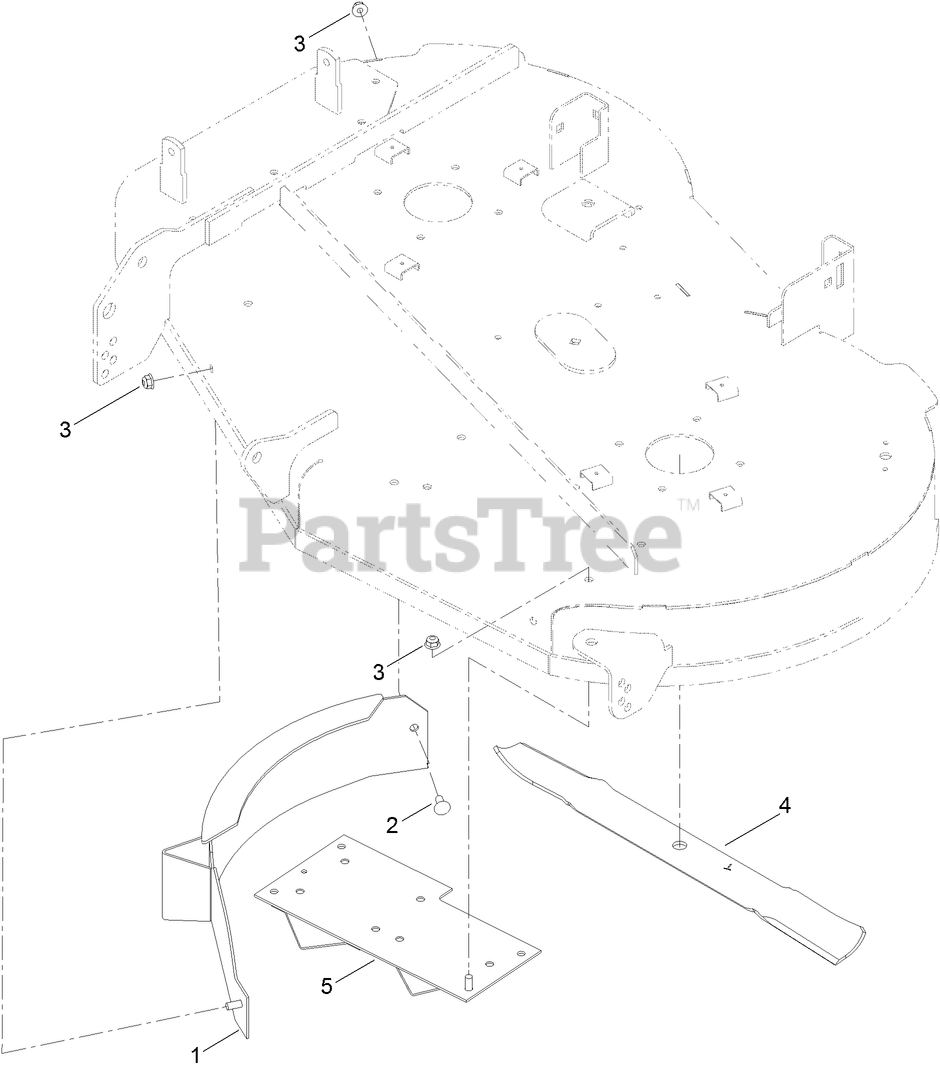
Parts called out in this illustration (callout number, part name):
1	BAFFLE ASM
2	BOLT-CARR
3	NUT-HF, NI
5	KICKER ASM
